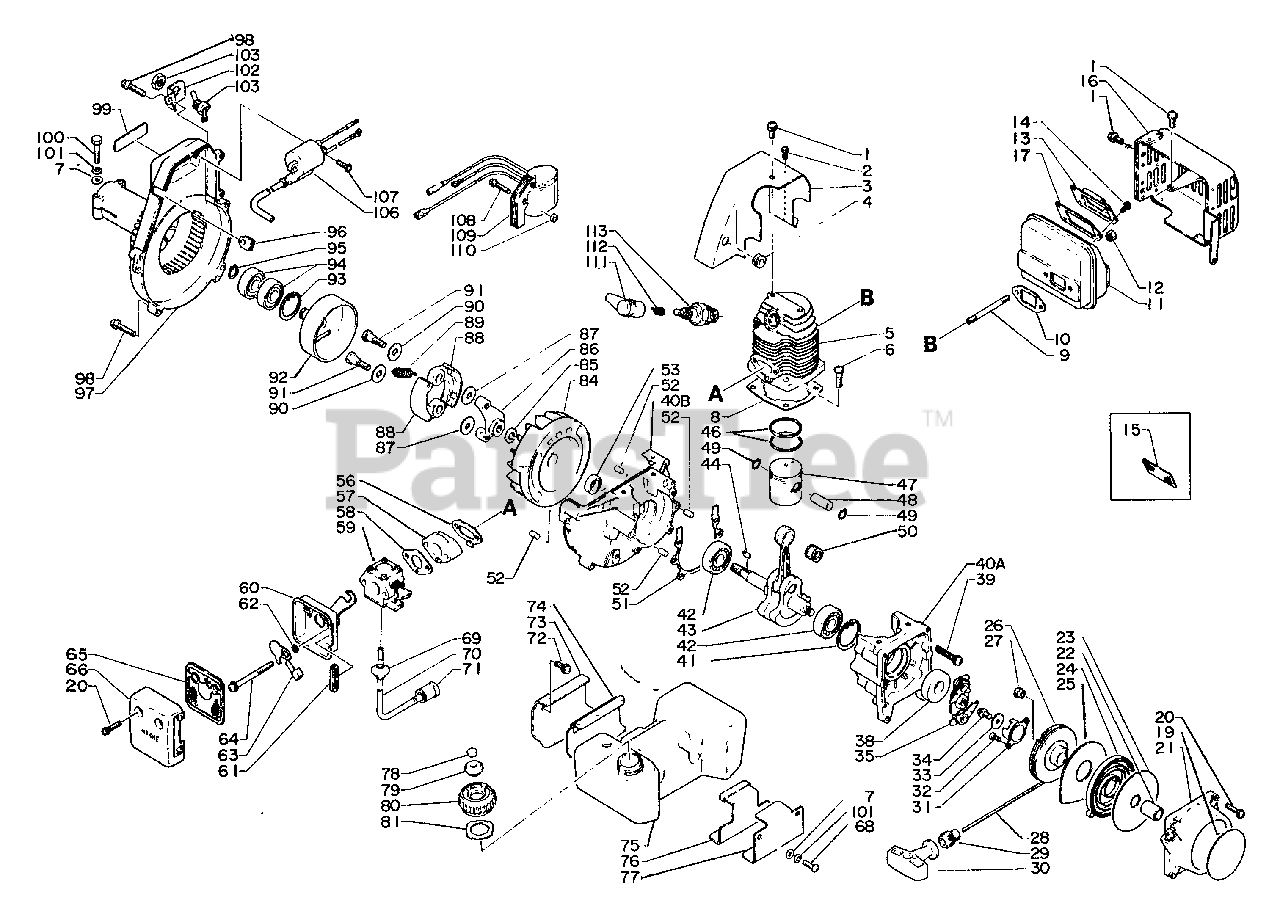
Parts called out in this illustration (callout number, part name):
1	SCREW 5×10
2	SCREW 4×10
3	COVER, CYLINDER
5	CYLINDER
6	SCREW 5×20
7	WASHER, FLAT 5.5×10×0.8
8	GASKET, CYLINDER
9	STUD
10	GASKET, EXHAUST
11	MUFFLER
12	LOCKNUT - 5
13	LID, MUFFLER
14	SCREW 4×8
15	SCREEN, SPARK ARRESTER
16	COVER, MUFFLER
17	GASKET, EXHAUST
19	LABEL - ECHO
20	SCREW 4×20
21	CASE, STARTER
23	PLATE, SIDE
24	SPRING, RECOIL
25	PLATE, SIDE
26	REEL, ROPE
27	CLIP, STARTER ROPE
28	ROPE, STARTER 3.5×850
29	GUIDE, ROPE
31	PAWL CATCHER
32	SCREW 4×8
33	WASHER 5.2×16×1.0
34	SCREW 5×10
35	STARTER PAWL ASSY
38	SEAL, OIL 18
39	SCREW 5×30
40	CRANKCASE KIT
40A	CRANKCASE KIT
40B	CRANKCASE KIT
41	RING, SNAP 35
42	BEARING, BALL 6202
43	CRANKSHAFT
46	RING, PISTON
47	PISTON
48	PIN, PISTON
49	RING, SNAP 8
50	BEARING, NEEDLE
51	GASKET, CRANKCASE
52	PIN, LOCATING 5×10
53	SEAL, OIL
56	GASKET, INTAKE
57	INSULATOR, INTAKE
58	GASKET, INTAKE
59	CARBURETOR - WA-87
60	CASE, AIR FILTER
62	WASHER 5.2×8×0.8T
63	SHUTTER, CHOKE
64	SCREW 5×60
65	FILTER, AIR
66	COVER, AIR FILTER
68	SCREW 5×14
70	PIPE, FUEL 3×5×150 BLACK
71	FILTER, FUEL
72	SCREW 5×14
73	BRACKET, FUEL TANK
74	CUSHION
75	TANK, FUEL
76	CUSHION
77	BRACKET, FUEL TANK
78	FILTER, CHECK VALVE
79	VENT ASSY
80	CAP
84	FLYWHEEL
85	WASHER, SPRING 8
86	BOSS, CLUTCH
87	WASHER 6.2×19×1.0
88	SHOE, CLUTCH
89	SPRING, CLUTCH
91	BOLT, CLUTCH
92	DRUM, CLUTCH
93	RING, SNAP Ø32
94	BEARING, BALL
95	RING, RETAINING - 12
97	COVER, FAN
98	SCREW 5×25
99	LABEL - MODEL
100	BOLT - 5×25
101	WASHER, SPRING 5
102	BRACKET, SWITCH
103	SWITCH, IGNITION
106	COIL, IGNITION
107	SCREW 4×15
108	SCREW 4×22
109	COIL, IGNITION
111	CAP, SPARK PLUG
112	TERMINAL, SPARK PLUG
113	SPARK PLUG - BM6A
